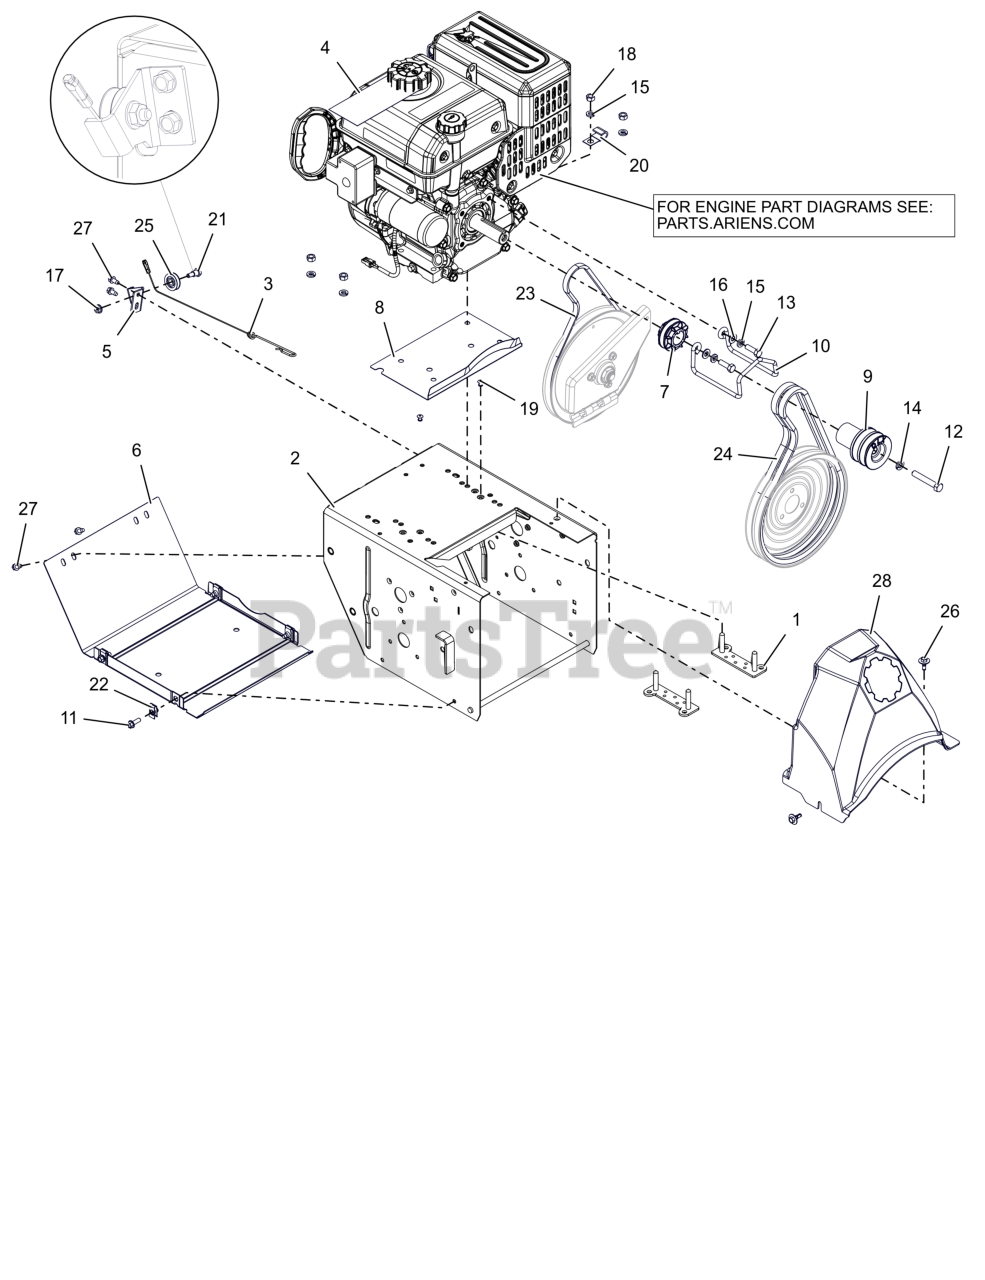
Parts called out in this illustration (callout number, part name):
1	STRAP, BOLT - SMALL ENGINE
2	FRAME, MAIN - 14GA DELUXE (ORANGE)
3	CABLE, LOWER TRACTION,SS & PRO
4	ENGINE, ARIENS AX252 120V/60W
5	BRKT, CABLE PULLEY
6	COVER, BOTTOM
7	SHEAVE, DRIVE
8	BAFFLE- WATER - SMALL
9	SHEAVE, ATTACHMENT - STANDARD 2 GRV
10	FINGER, BELT
11	BLT, HWH .25-20X.75 G5 ZCC
12	BLT, HEX .38-24X2.25 G5 ZCC
13	BLT, HEX 0.3125-24X1 G5 ZCC
14	WSHR,LK-REG .375X.094 ZCC
15	WSHR, LK-HVY .312X.097 ZCC
16	WSHR,FLT .344X.688X.065 ZCC
17	NUT-LK-TOP-FLG .250-20 GF ZCC
18	NUT, HEX .312-18 ZCC
19	RVT, POP .1875 ZCC
20	J-CLAMP
21	BOLT, SHLDR -.375 X .375 X .25-20
22	NUT-RTNR .25-20X.56
23	V-BELT, 3L-WRAPPED
24	V-BELT, HA-RAW EDGE (SET)
25	PULLEY, CABLE
26	SCR-TAP .25-20X.5 CAPTIVE
27	SCR-TAP .25-20X.50 HWH ZCC
28	COVER, BELT - SMALL
